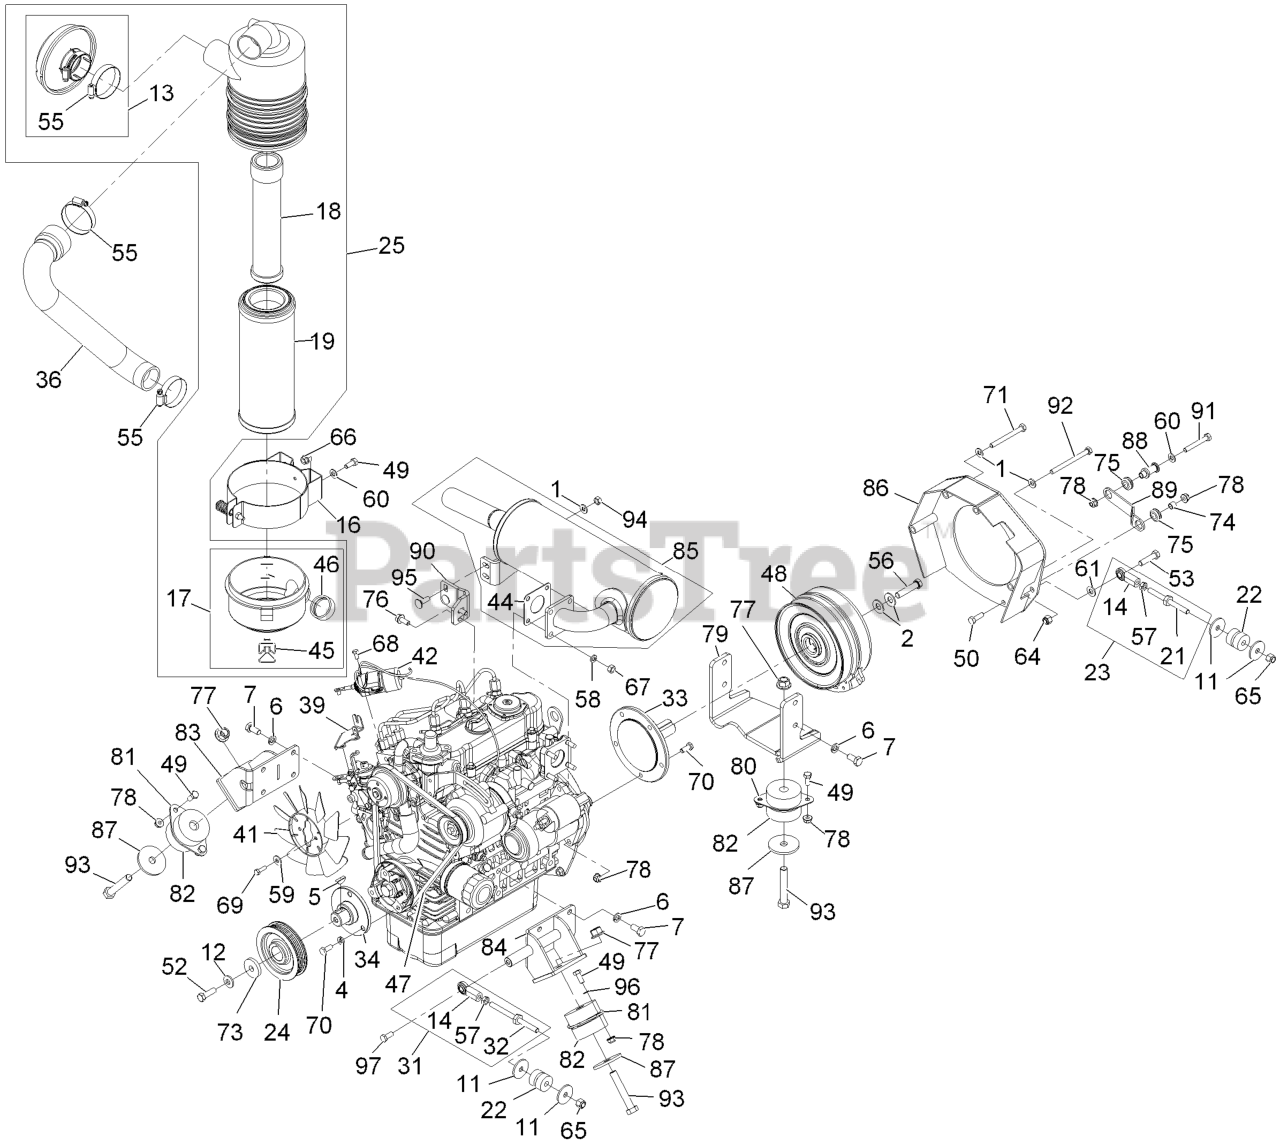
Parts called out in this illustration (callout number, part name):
1	WASHER-SPRING
2	WASHER-SPRING
4	WASHER-LOCK
5	KEY-WOODRUFF
6	Washer-Lock M10
7	SCREW-CAP
12	WASHER-BELLEVILLE
13	HOOD-CLEANER, 2" AIR INTA
14	JOINT-BALL, END
16	BRACKET-FILTER, AIR
17	COVER-FILTER, AIR
18	FILTER-AIR, SAFETY
19	FILTER-AIR
21	LINK,REAR A-T AXIAL
22	ISOLATOR-LINK
23	BALL JOINT LINK ASM
24	SHEAVE,5K 4"PD POLY-V
25	FILTER-AIR
31	ASM, A-T LINK
32	LINK,REAR A-T AXIAL
33	SHAFT,KUBOTA 902 STUB
34	HUB,PUMP DRIVE
36	HOSE,AIR INTAKE D902(8015
39	BRACKET-SUPPORT, THROTTLE
41	FAN,COOLING 7"
42	SOLENOID,FUEL
44	GASKET-MUFFLER
45	CLIP-CLEANER, AIR
46	EJECTOR, NELSON AIR CLEAN
47	BELT,KUBOTA 902 ALT
49	SCREW-HH
50	SCREW-HH
52	SCREW-HH
53	SCREW-HH
55	CLAMP-HOSE
56	SCREW-HH
57	NUT-HJ
58	WASHER-LOCK
59	WASHER-FLAT
60	WASHER-PLAIN
61	WASHER-FLAT
64	NUT-LOCK, NI
65	NUT-LOCK
67	NUT-HEX
68	SCREW-HH
69	SCREW-HH
70	SCREW-HH
71	SCREW-HH
73	WASHER-CLUTCH
75	GROMMET
76	SCREW-HHF
77	Nut-Lock 1/2-13
78	NUT-HF, NI
79	BRACKET,ENGINE MOUNT
80	FLANGE ASM
81	FLANGE-11GA
82	ISOLATOR,ENGINE
83	ENGINE MOUNT-RH
84	ENGINE MOUNT-LH
85	ASM,KUBOTA MUFFLER
86	WLD,FLYWHEEL COVER
88	CLUTCH STANDOFF
89	CLUTCH LINK
90	BRACKET-MUFFLER
91	SCREW-HH
92	SCREW-HH
93	SCREW-HH
94	NUT-HEX
95	BOLT-CARR
96	WASHER-LOCK
97	SCREW-HH, LOCK
